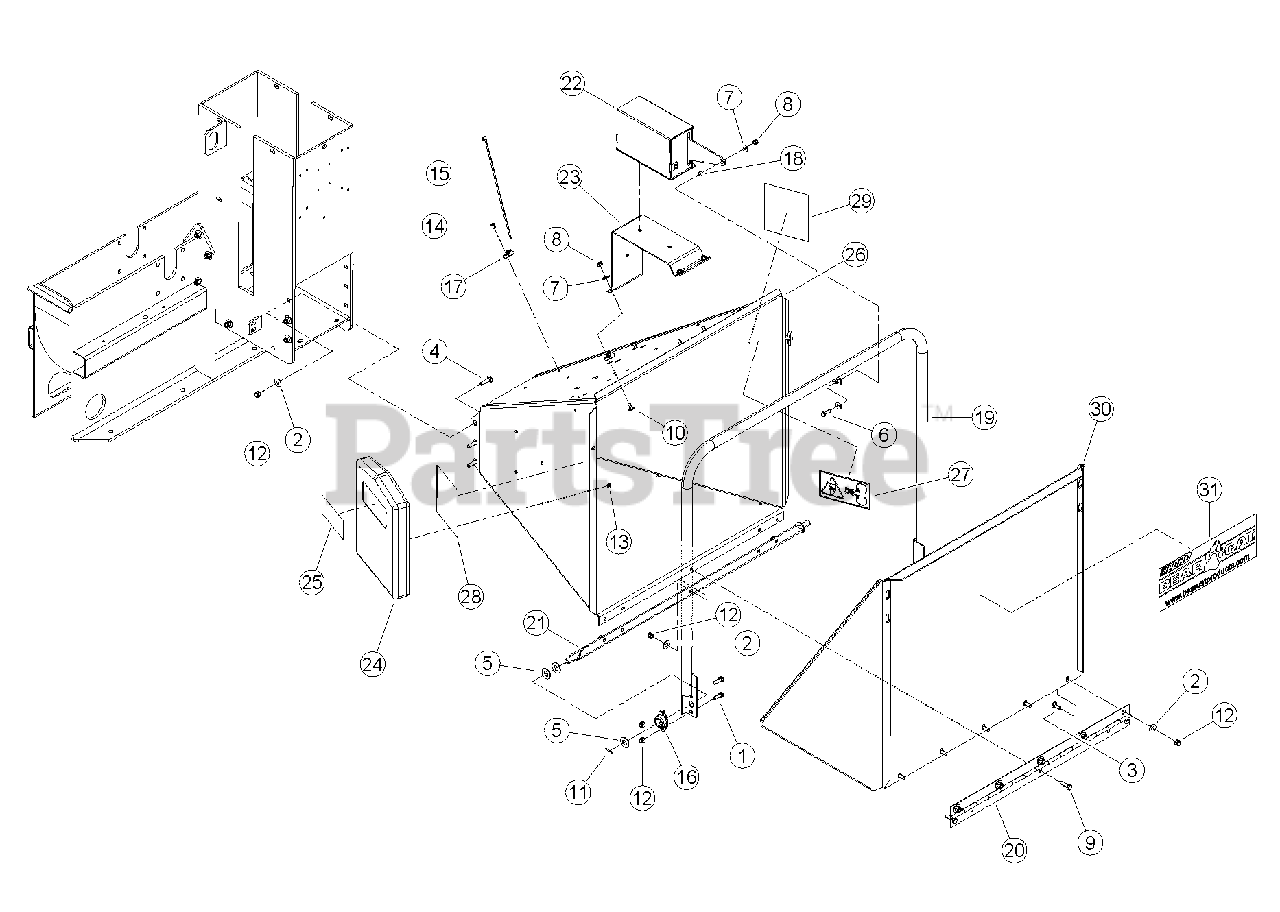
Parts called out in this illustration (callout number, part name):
1	BOLT, 3/8 X 1 HEX HD GR5 ZP
2	WASHER, 3/8 FLAT ZP
3	BOLT, 3/8 X 1 CRG GR5 ZP
4	BOLT, 3/8 X 1-1/2 CRG GR5 ZP
5	WASHER, 5/8 SAE FLAT ZP
6	BOLT, 5/16 X 1 HHCS GR5 NC ZP
7	WASHER, 5/16 FLAT ZP
8	NUT, 5/16 NE NYLOCK ZP
9	BOLT, 3/8 X 1-1/4 HEX HD GR5 ZP
10	BOLT, 5/16 X 3/4 CRG GR5 NC ZP
11	PIN, 1/8 X 1.00 ZP COTTER
12	NUT, 3/8 NE NYLOCK ZP
13	RIVET, AL BLIND 1/4 X 1/2 DOME HEAD
14	RIVET, AL BLIND 1/4 X 3/4 DOME HEAD
15	STRAP, 11 INCH BLACK TIE
16	BEARING, SIDE FLNG MOUNT 5/8
17	CLAMP, CABLE MOUNT
18	SPACER, IDLER PIVOT
19	WELDMENT, CONTROL ARM
20	HINGE, EXTENSION TRAY
21	WELDMENT, CONTROL PIVOT
22	ASSEMBLY, SWITCH BOX
23	MOUNT, SWITCH BOX
24	ASSEMBLY, MANUAL CONTAINER SERVICE PART
25	DECAL, MUTILINGUAL MANUAL
26	ASSEMBLY, BIG CHIPPER CHUTE SERVICE PART
27	DECAL, BLADE DANGER ISO
28	DECAL, FEED POSITION
29	DECAL, FEED POSITION
30	ASSEMBLY, CHUTE EXTENSION TRAY SERVICE PART
31	DECAL, BEARCAT WEB
